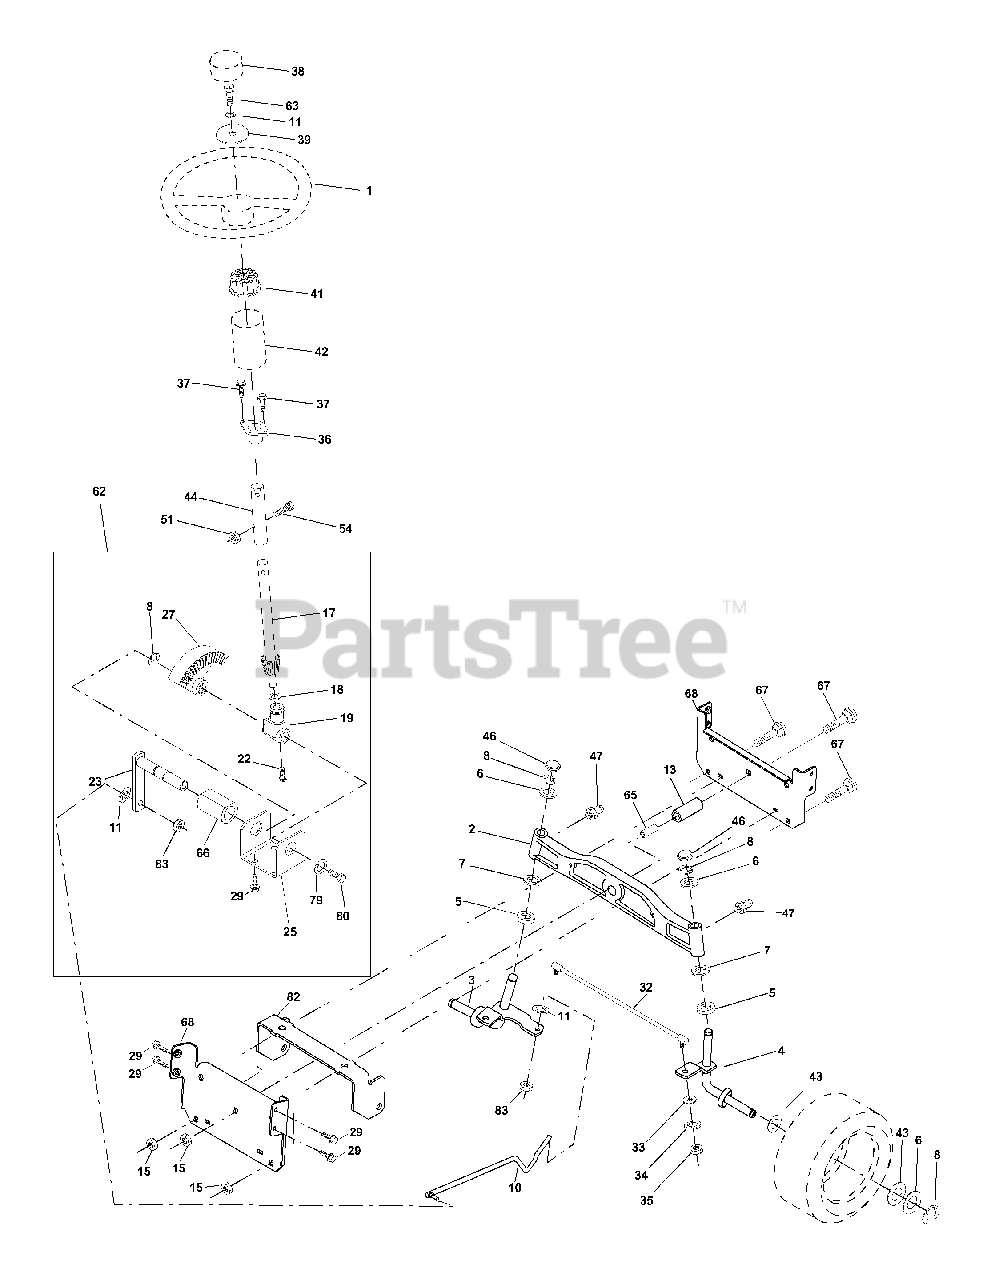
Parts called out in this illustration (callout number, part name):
1	Wheel Steering
2	Axle Cast LT Machined
3	Spindle Asm Cast LH
4	Spindle Asm Cast RH
5	Bearing Race Thrust Harden
6	Washer 25/32 X 1-5/8 X 16 Ga
7	Washer 27/32 X 1-1/4 X 16 Ga
8	Ring Klip #t5304-75
11	Washer Lock Hvy Hlcl Spr 3/8
13	Spacer Brg Axle Front
15	Nut Hex Flange Lock Yel D
17	Shaft Asm Strg Private Label
18	Washer Thrust 515x 750x 033
19	Support Shaft
22	Screw Hex Wshhd Torx
23	Shaft Asm Pittman
25	Bracket Steering
27	Gear Sector 22 Teeth
29	Screw 3/8-16x3/4
32	Rod Tie
33	Washer 11/32 x 3/4 x 16 Ga.
34	Washer Lock Hvy. Helical 5/16 SD
35	Nut Crown Lock 5/16-18
36	Bushing Strg
37	Screw TT #32.5 x 5 x 3/8 Flange
38	Cap Wheel Steer
39	Washer 13/32 x 1-1/20 x 11 Ga.
40	Nut Lock Center 3/8-24 Unf
41	Adaptor Wheel Strg
42	Boot Dash Steering
43	Washer 25/32 X 1 1/4 X 16 Ga
44	Extension Steering Non-adjust
46	Cap Spindle Fr Top Blk
47	Fitting Grease
51	Nut Lock Hex W/Ins 5/16-18 UNC
54	Bolt Fin Hex 5/16-18 UNC x 1-1/4
62	Steering Assembly
63	Bolt Fin Hex 3/8-16 UNC x 1 Gr. 5
65	Spacer, Brace Axle
66	Bearing Arm Pittman
67	Bolt Rdhd Sqnk 3/8-16 x 2-1/4
68	Brace, Axle
79	Washer 13/32 x 1-1/4 x 12 Ga.
80	Bolt Hex Nylon 3/8-16 x 3/4
82	Bracket Susp Chassis Front 15"
